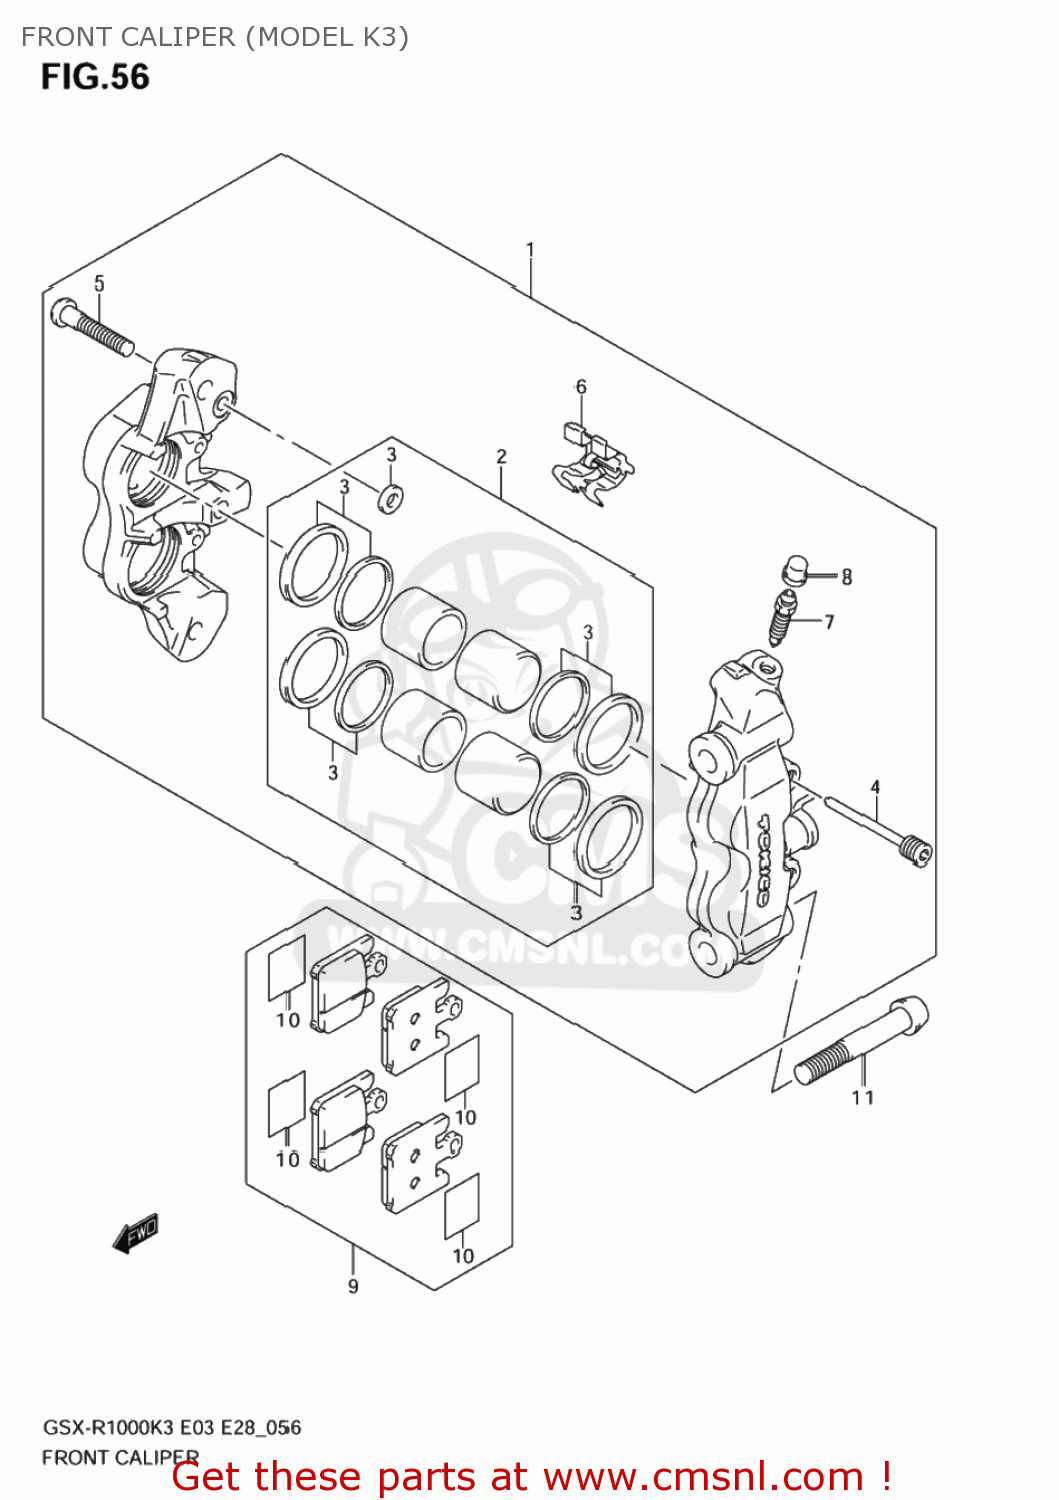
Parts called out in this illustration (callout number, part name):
1	CALIPER ASSY,FR,R
2	PISTON SET
3	SEAL SET,PISTON
4	PIN,PAD
5	BOLT
6	SPRING,PAD
7	BLEEDER
8	CAP,BLEEDER PLUG
9	PAD SET (NAS)
10	TAPE
11	BOLT(10X60)
